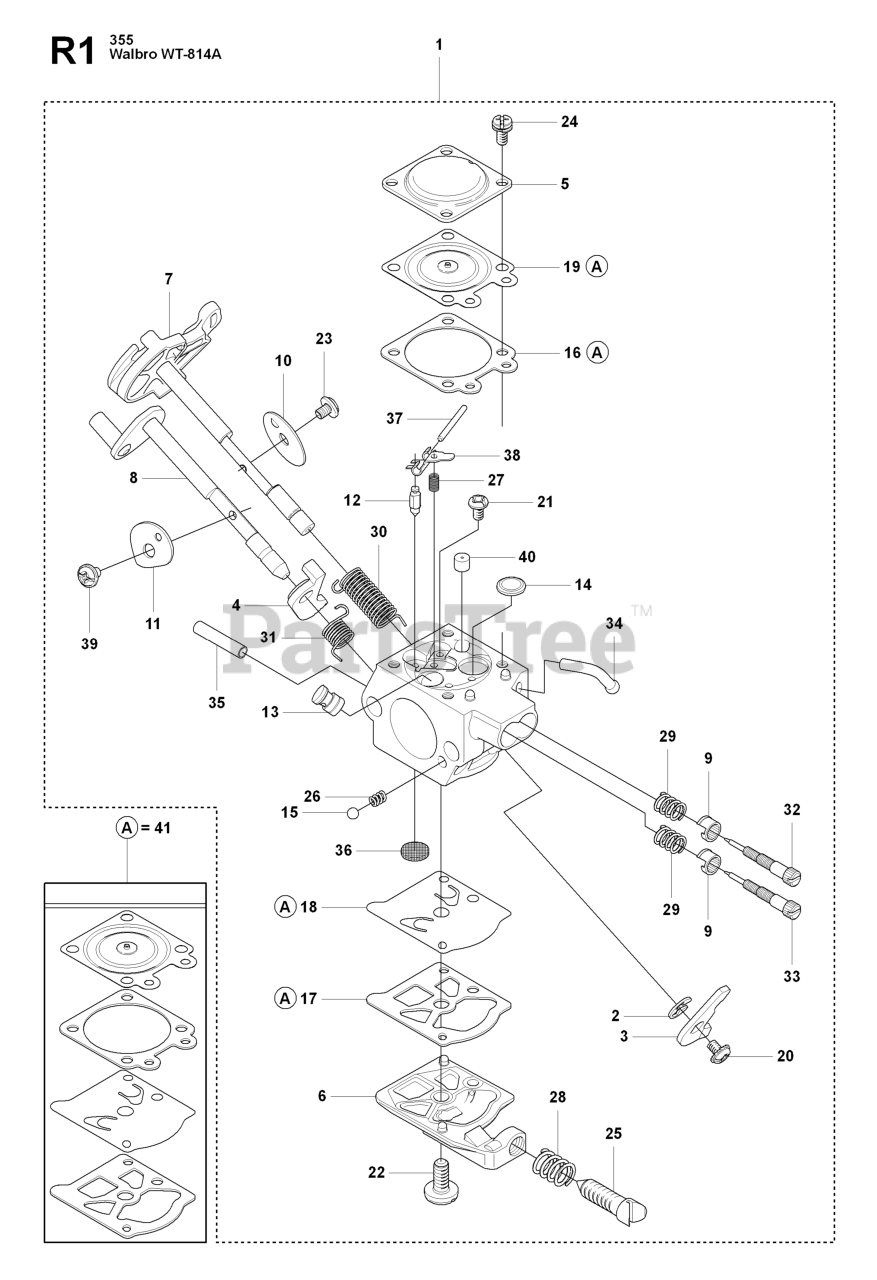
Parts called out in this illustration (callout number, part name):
1	CARBURETOR WT-814A
2	E CLIP
5	DIAPHRAGM COVER
9	LIMITER CAP
12	INLET NEEDLE
14	PLUG
18	DIAPHRAGM, FUEL PUMP
19	METERING DIAPHRAGM
23	SCREW
24	RP SCREW W/ WASHER
28	SPRING
36	FUEL INLET SCREEN
37	FULCRUM PIN
41	GASKET SET
